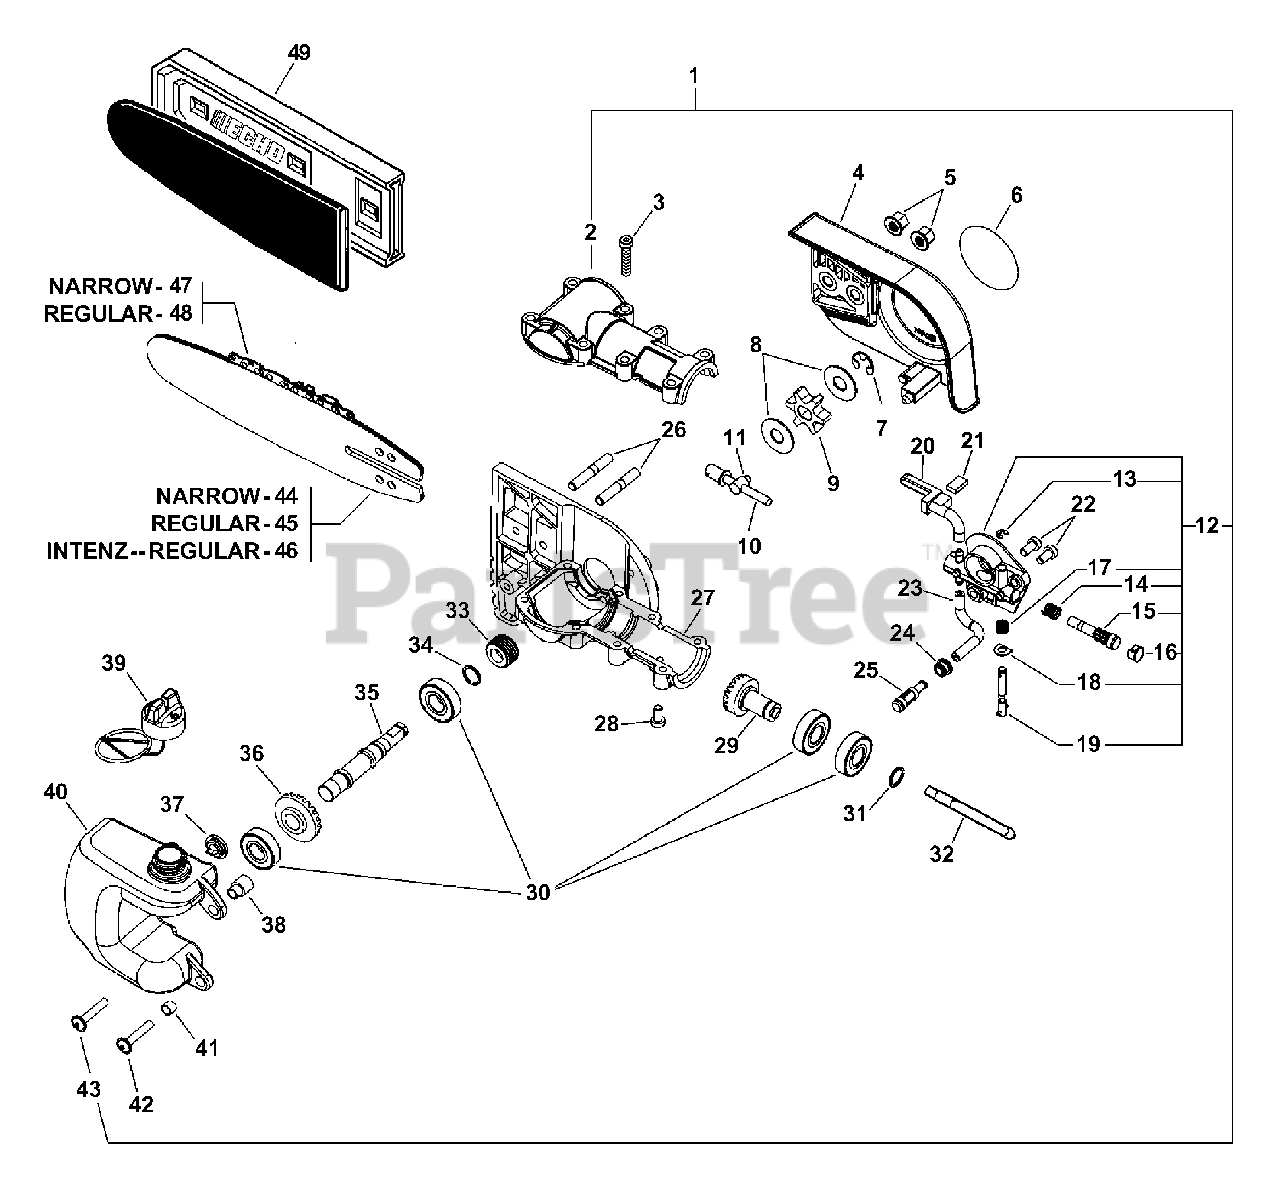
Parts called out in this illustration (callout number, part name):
1	OILER GEAR BOX ASSY
2	CASE, GEAR - UPPER Ø35
3	SCREW M5×.25
4	GUARD, SPROCKET
5	NUT, FLANGE M6
6	LABEL, ECHO
7	RING, RETAINING Ø0.300
8	WASHER 10.2×24.5×1.2
9	SPROCKET, DRIVE
11	TENSIONER, CHAIN
12	AUTO-OILER ASSY
15	PLUNGER ASSY
16	CAP, OIL PUMP
19	ADJUSTER, OILER
20	PIPE, OIL OUTLET
21	PAD, FOAM
22	SCREW M5×.8×10
23	PIPE, IMPULSE 3×6×75
24	GROMMET
25	FILTER, OIL
26	BOLT, STUD 6
27	CASE, GEAR
28	SCREW M5×.8×10
29	GEAR, BEVEL
30	BEARING, BALL 6201
31	RING, SNAP Ø12
32	CONNECTOR, DRIVE SHAFT
33	GEAR, WORM
34	RING, SNAP Ø12
35	SHAFT, GEAR
36	GEAR, BEVEL
37	VENT ASSY
38	COLLAR 6
39	CAP ASSY, OIL
40	TANK, OIL
41	SPACER 6.2×7.8×6
42	SCREW 5×16 MM
43	SCREW 5×28
44	GUIDE BAR - 12"
45	GUIDE BAR - 12"
46	GUIDE BAR - 12" -- INTENZ
47	SAWING CHAIN - 90SG - 12" -- MICRO-LITE
48	SAWING CHAIN - 91VS - 12" -- LOW PROFILE
49	SCABBARD
